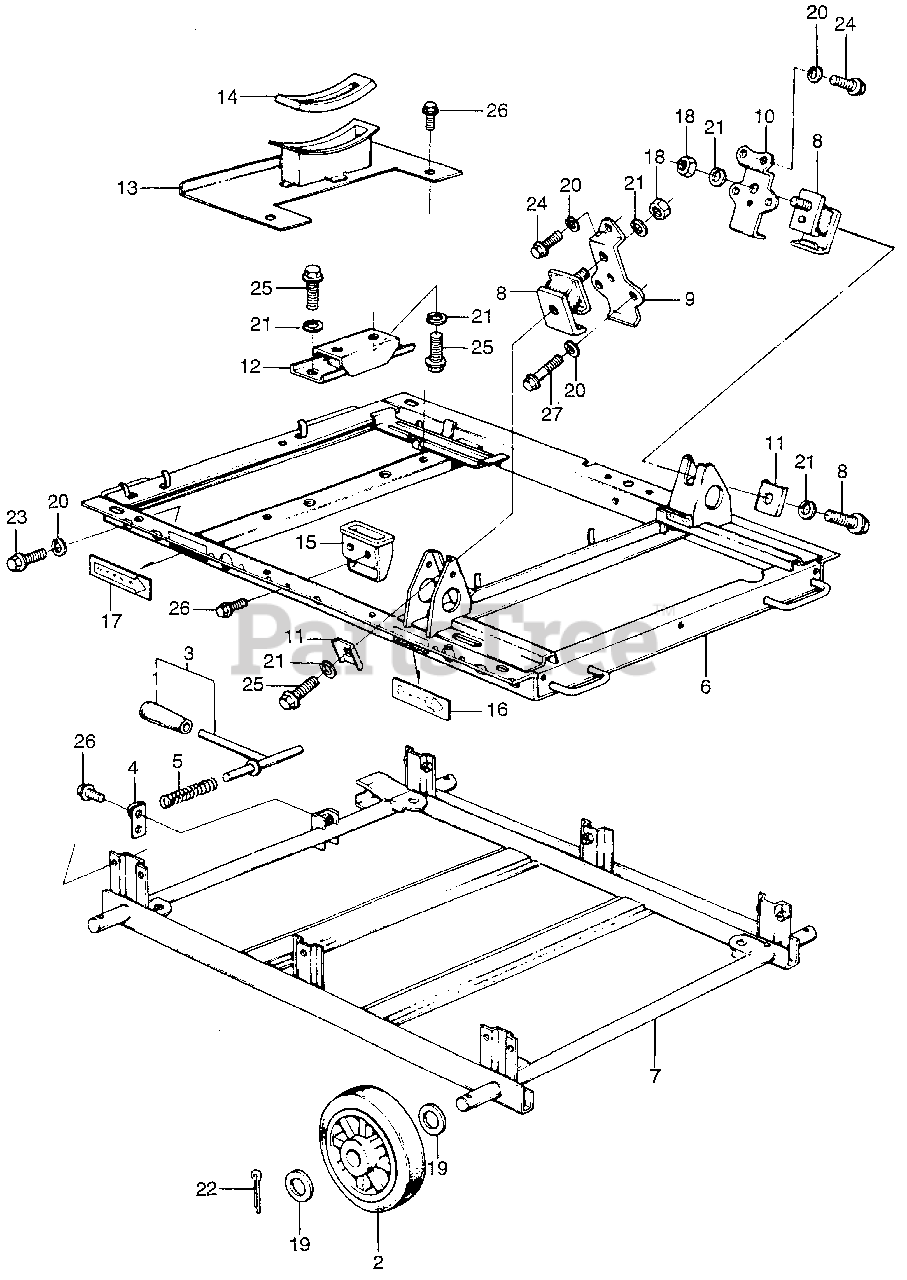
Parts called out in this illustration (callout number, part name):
1	GRIP, LEVER
2	WHEEL
3	STOPPER, WHEEL
4	HOLDER, STOPPER
5	SPRING, WHEEL STOPPER
6	BED *NH83L* (OFF BLACK)
7	FRAME (LOWER) *NH83L* (OFF BLACK)
8	RUBBER, FR. ENGINE MOUNT (NOT AVAILABLE)
9	SEAT, FR. RUBBER SETTING
10	SEAT, RUBBER SETTING
11	STIFFENER, FR. RUBBER SETTING
12	RUBBER, ALTERNATOR SETTING
13	COVER, ALTERNATOR (LOWER)
14	SHEET, COVER (LOWER)
15	DUCT B, SEPARATOR
16	MARK, OIL DRAIN
17	MARK, COOLANT DRAIN
18	NUT, HEX. (10MM)
19	WASHER, FLAT (20MM)
20	WASHER, SPRING (8MM)
21	WASHER, SPRING (8MM)
22	PIN, COTTER (4.0X30)
23	BOLT, FLANGE (8X16)
24	BOLT, FLANGE (8X20)
25	BOLT, FLANGE (10X20)
26	BOLT, FLANGE (6X12)
27	BOLT, FLANGE (8X28)
